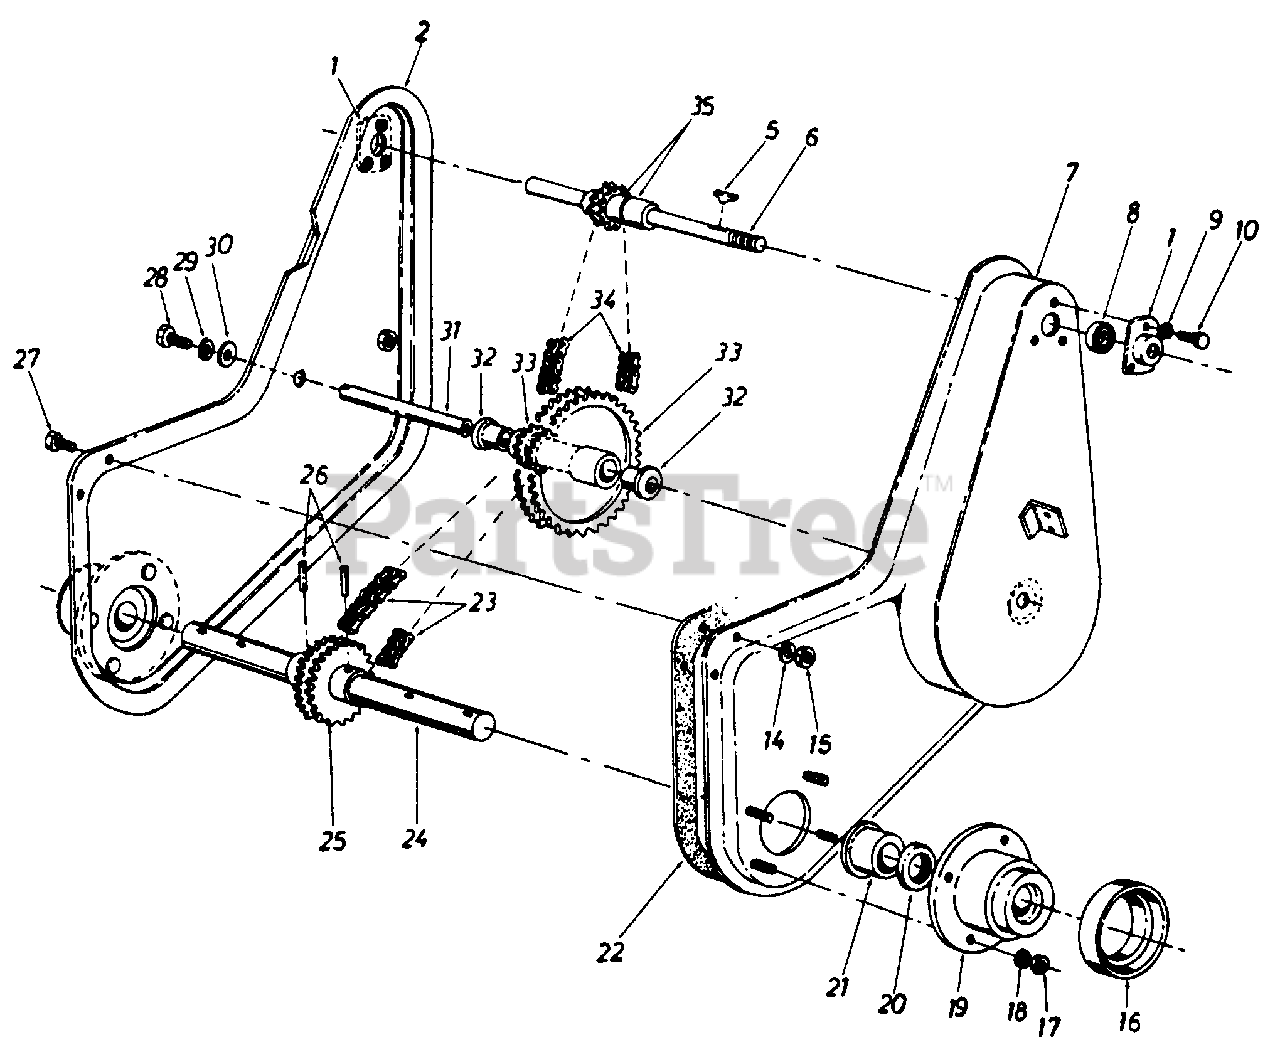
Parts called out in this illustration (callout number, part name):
1	Bearing Housing 1.375 Dia.
6	Input Shaft Assembly
9	L-Wash. 1/4" I.D.
10	Hex Bolt 1/4-20 x .62 Lg.
14	L-Wash. 1/4" I.D.
15	Hex Cent. L-Nut 1/4-20 Thd.
16	Dust Cap Cover
17	Hex Cent. L-Nut 5/16-18 Thd.
18	L-Wash. 5/16 I.D.
19	Cast Bearing Housing
20	Oil Seal
21	Flange Bearing 1.25 I.D. x 1.75" O.D.
23	Roller Chain #40-2 x 34 0n Lg.
25	Double Sprocket T242 Teeth 1/2" Pitch
26	Spiral Pin 3/8 Dia. x 2.00" Lg.
27	Hex Bolt 1/4-20 x .62" Lg.
28	Hex Bolt 5/16-18 x .75 Lg.
29	L-Wash. 5/16" I.D.
30	Fl-Wash. 5/16" I.D.
31	Sprvcket Shaft
32	Flange Bearing .62 I.D. x .75" O.D.
33	Double Sprocket Assembly
34	Roller Chain #35-2 x 36.75 Lg.
35	Spacer 5/8 I.D. x 718 O.D.
